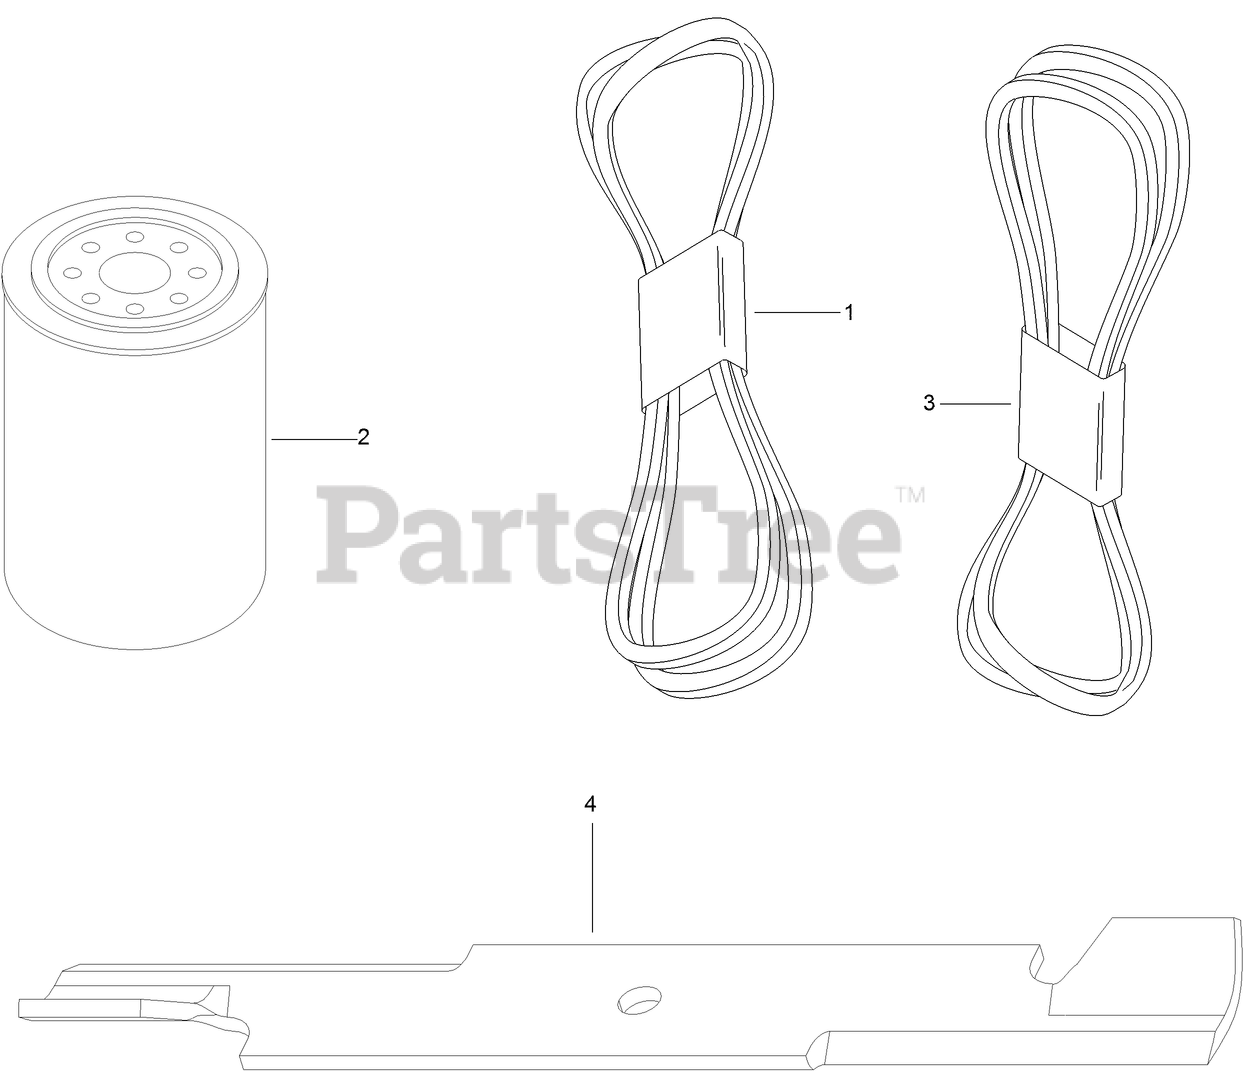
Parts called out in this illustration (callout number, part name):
1	BELT-V
2	FILTER-OIL, HYDRAULIC
3	BELT-V
4	BLADE-HI FLOW, 24.5 INCH
